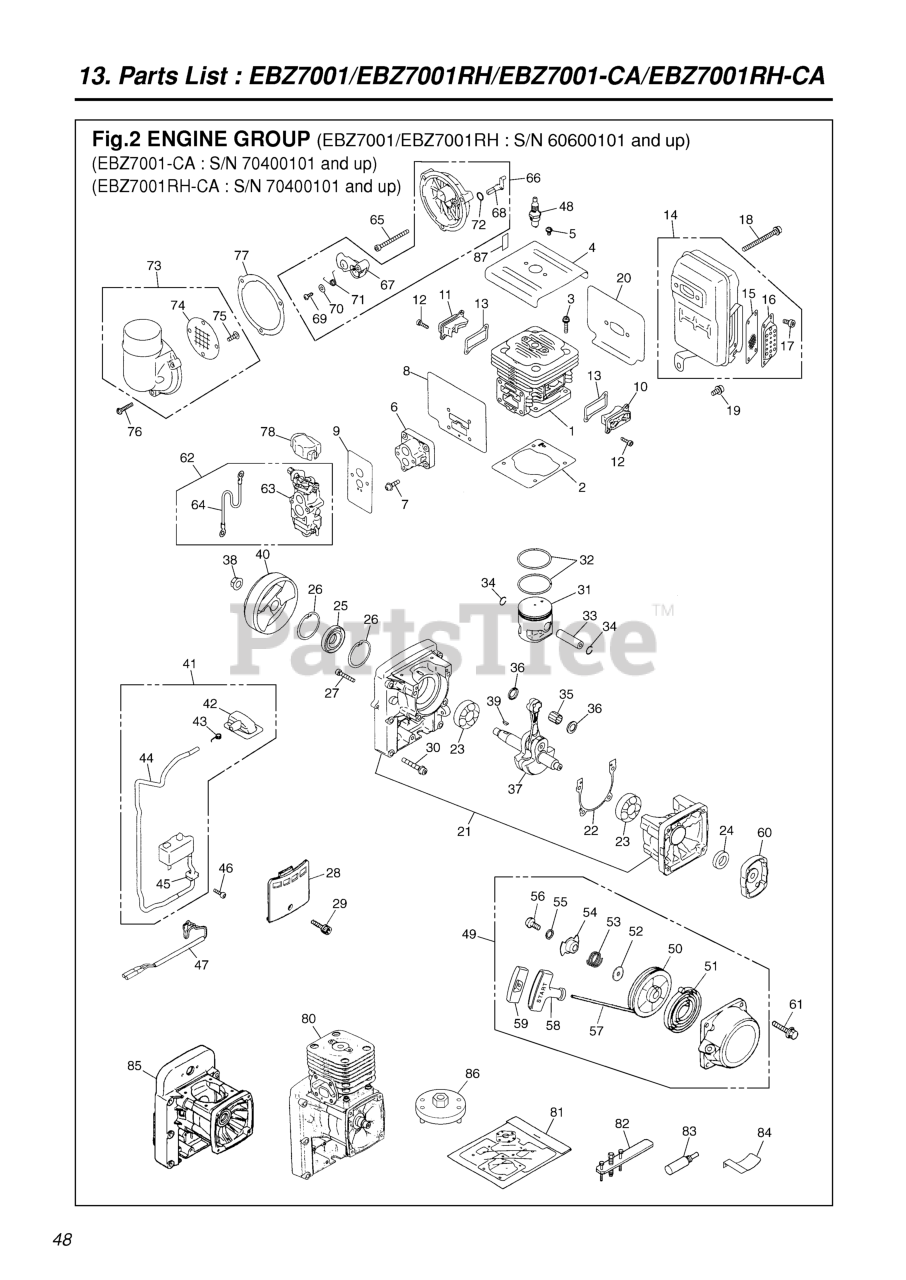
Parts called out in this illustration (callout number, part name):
1	CYLINDER
2	GASKET, BASE
3	BOLT
4	PLATE, CYL
5	SCREW TORX
6	INSULATOR
7	BOLT
8	GASKET, INSULATOR
9	GASKET, CARB.
10	COVER, TR (S)
11	COVER, TR (F)
12	BOLT TORX
13	GASKET, TR
14	Muffler Assy
15	Arrester
16	Diffuser
17	Bolt
18	BOLT TORX
19	BOLT
20	GASKET
21	CRANKCASE-CASE
22	GASKET, CASE
23	BEARING
24	SEAL
25	SEAL
26	SNAP RING
27	BOLT
28	COVER
29	BOLT TORX
30	BOLT TORX
31	PISTON
32	PISTON RING
33	PIN
34	SNAP RING
35	BEARING
36	WASHER
37	CRANKSHAFT-C
38	NUT, M10
39	KEY
40	ROTOR
41	COIL ASSY
42	CAP
43	SPRING
44	TUBE
45	GROMMET
46	BOLT TORX
47	CORD-C
48	USE T110873110
49	RECOIL ASSY (RPLS -7511)
50	REEL (REPLACES -75C1)
51	SPRING
52	WASHER (REPLACES -75M0)
53	SPRING, FRICTION (RPLS. -75L1)
54	PLATE, FRICTION (RPLS. -75K1)
55	WASHER (REPLACES -75W0)
56	SCREW
57	ROPE
58	KNOB
59	COVER KNOB
60	PULLEY (RPLS 848-H00-7520)
61	BOLT, TORX
62	CARBURETOR SET
63	CARBURETOR-A
64	Cord
65	BOLT
66	CUP ASSY
67	PLATE, CHOKE
68	LEVER
69	SCREW
70	WASHER
71	SPRING
72	O-RING
73	COVER ASSY. (REPLACES -8340)
74	SCREEN
75	SCREW
76	SCREW
77	GASKET,CUP
78	COVER
80	SHORT BLOCK
81	GASKET KIT
82	PULLER ASSY
83	STOPPER (TOOL)
84	GAUGE
85	CRANKCASE-A
86	PULLER
87	LABEL, CHOKE
